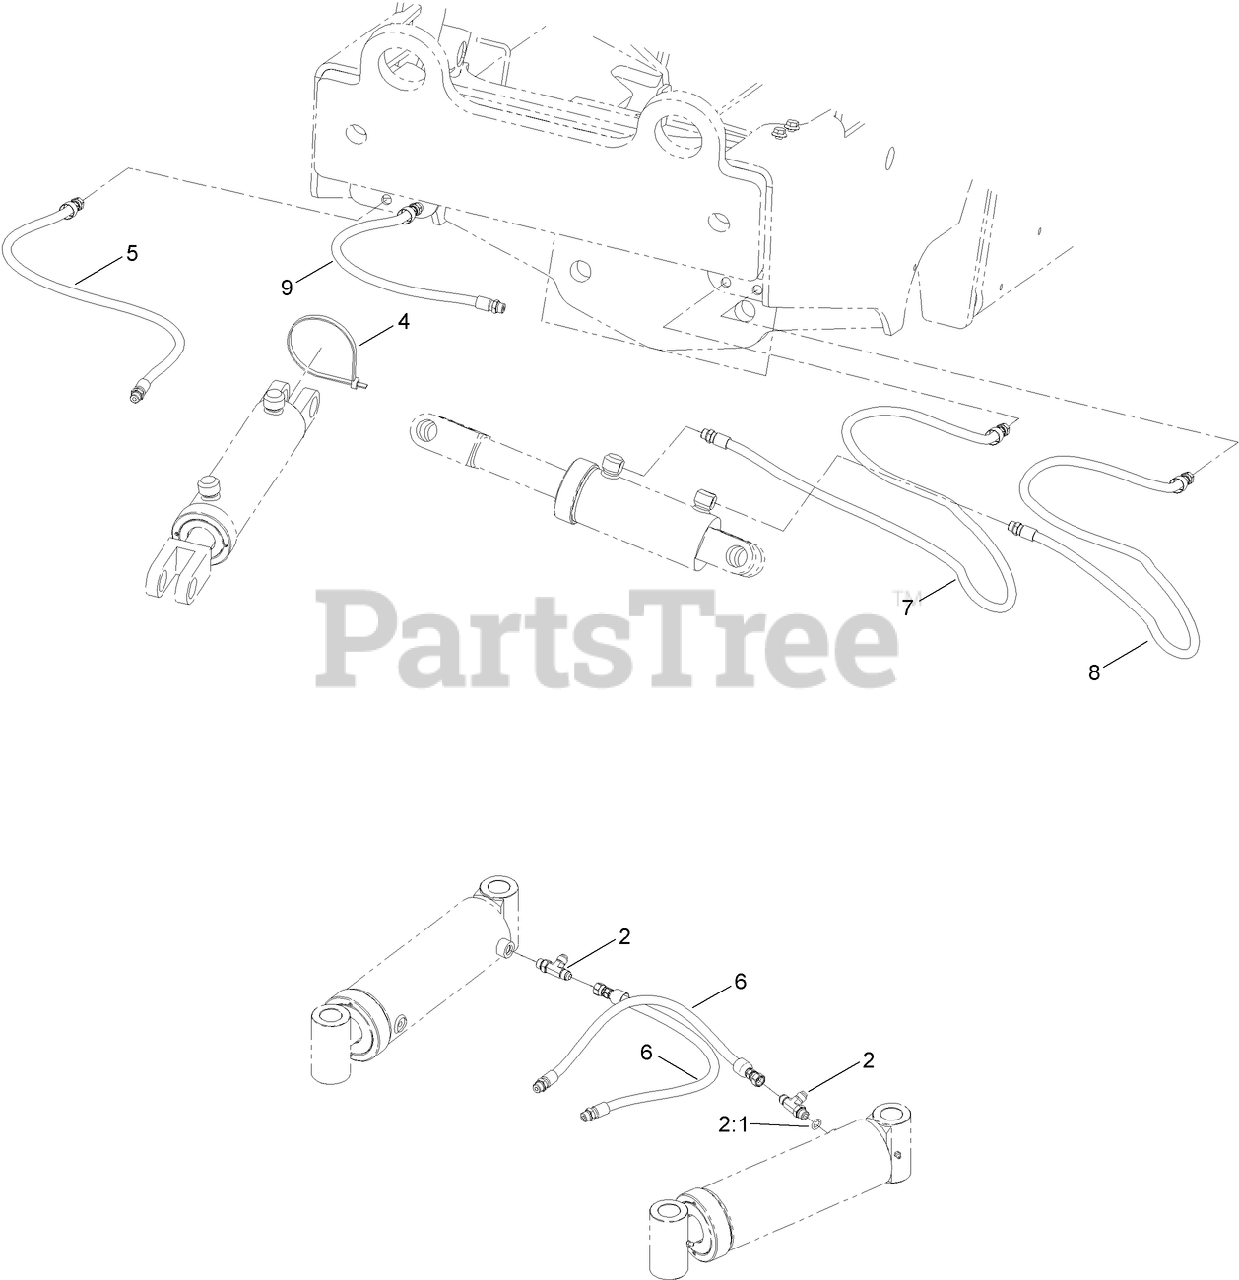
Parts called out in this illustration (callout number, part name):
2	FITTING-TEE
2:1	O-RING
4	TIE-CABLE
5	HYD HOSE ASM, HP
6	HYD HOSE ASM, HP
7	HYD HOSE ASM
8	HYD HOSE ASM, HP
9	HYD HOSE ASM, HP
